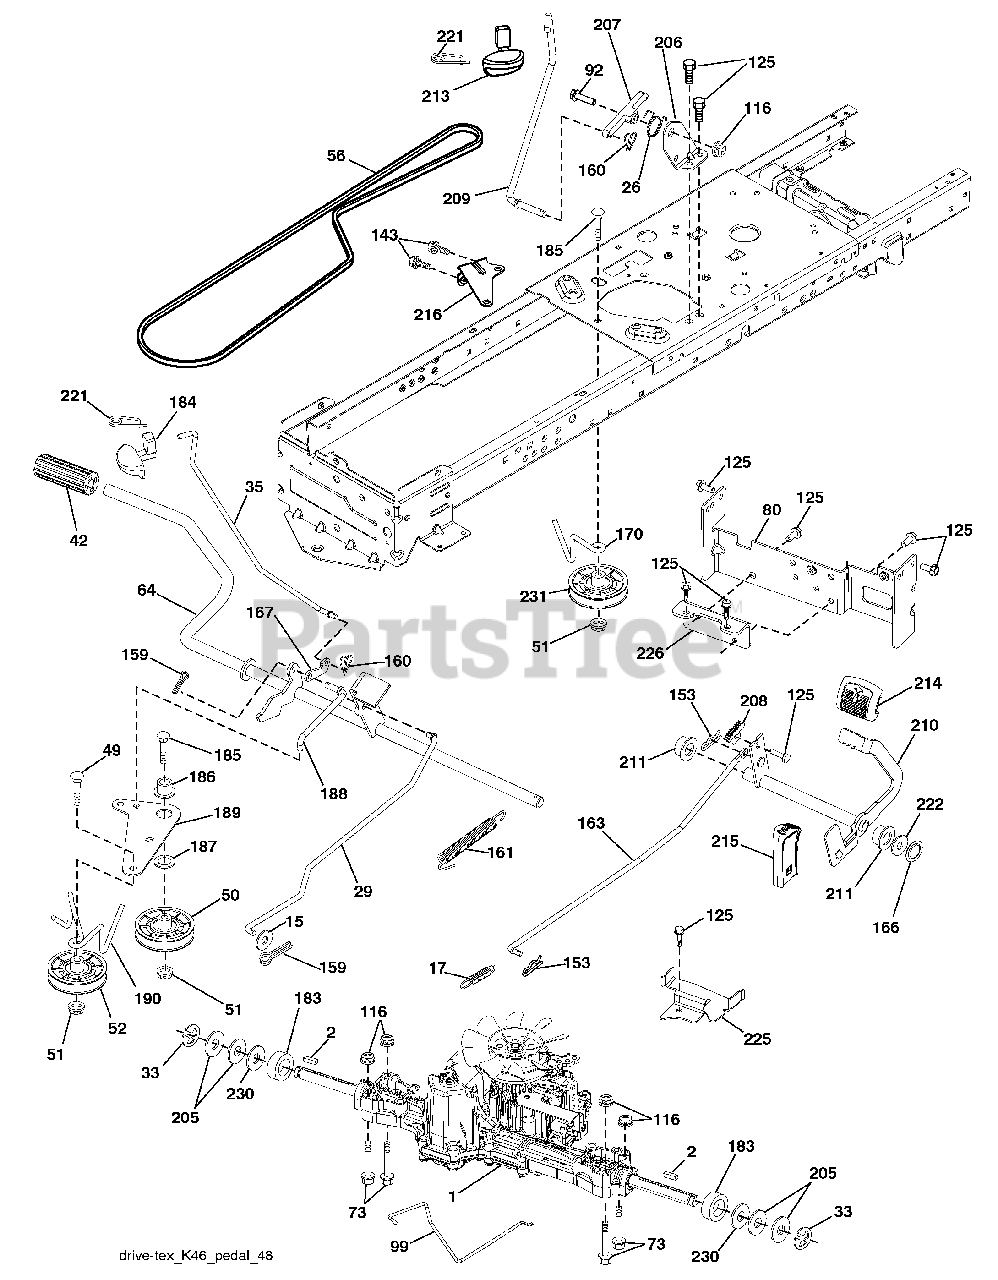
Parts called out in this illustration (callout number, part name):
1	Transaxle, Tufftorq K46BT
2	Key Square
15	Washer 13/32 x 13/16 x 16 Ga.
17	Spring, Brake
26	Spring Return Cruise
29	Rod, Brake
35	Rod, Brake, Park
42	Cover, Foot Pedal
50	Pulley Idler Flat
51	Lock Nut 3/8-16
52	Idler V-Groove 910" Offset
56	V-Belt, Drive
64	Shaft Asm. Pedal Brake Control
73	Bolt Hex 5/16-18 Gr. 5
80	Strap Torque
92	Bolt Fin Hex 5/16-18 unc x 1.25
99	Rod Spring Bypass
116	Nut Lock Hex Flange 5/16-18
125	Screw 5/16-18 x 3/4
143	Screw 5/16-18 x 1/2
153	Retainer Spring 1"
159	Pin Cotter 1/8 x 3/4
160	Retainer Clip
161	Spring, Return, Clutch
163	Rod Control
166	Nut Push
167	Latch Brake Parking
170	Keeper V-Idler
183	Spacer Axle
184	Handle Parking Brake
186	Spacer Retainer
187	Washer
188	Link Clutch Ground Drive
189	Bellcrank Ground Drive
190	Keeper Bellcrank Ground Drive
205	Washer 25/32 x 1-5/8 x 16 Ga.
206	Bracket Mount Latch Cruise
207	Latch Control Cruise
208	Gear Sector Control Cruise
209	Rod Control Cruise
210	Rocker Asm. Pedal Control
211	Bearing Nylon
213	Knob Control Cruise
214	Pedal Forward Pad
215	Pedal Reverse
216	Bracket Pulley Idler
221	Retainer Spring Clip Handle
222	Washer 21/32 x 1-1/4 10 Ga.
225	Keeper Belt Transaxle
226	Bracket Mount Torque
230	Washer Harden .793 x 1.637 x 060
231	Idler V-Groove 1.688" Offset
